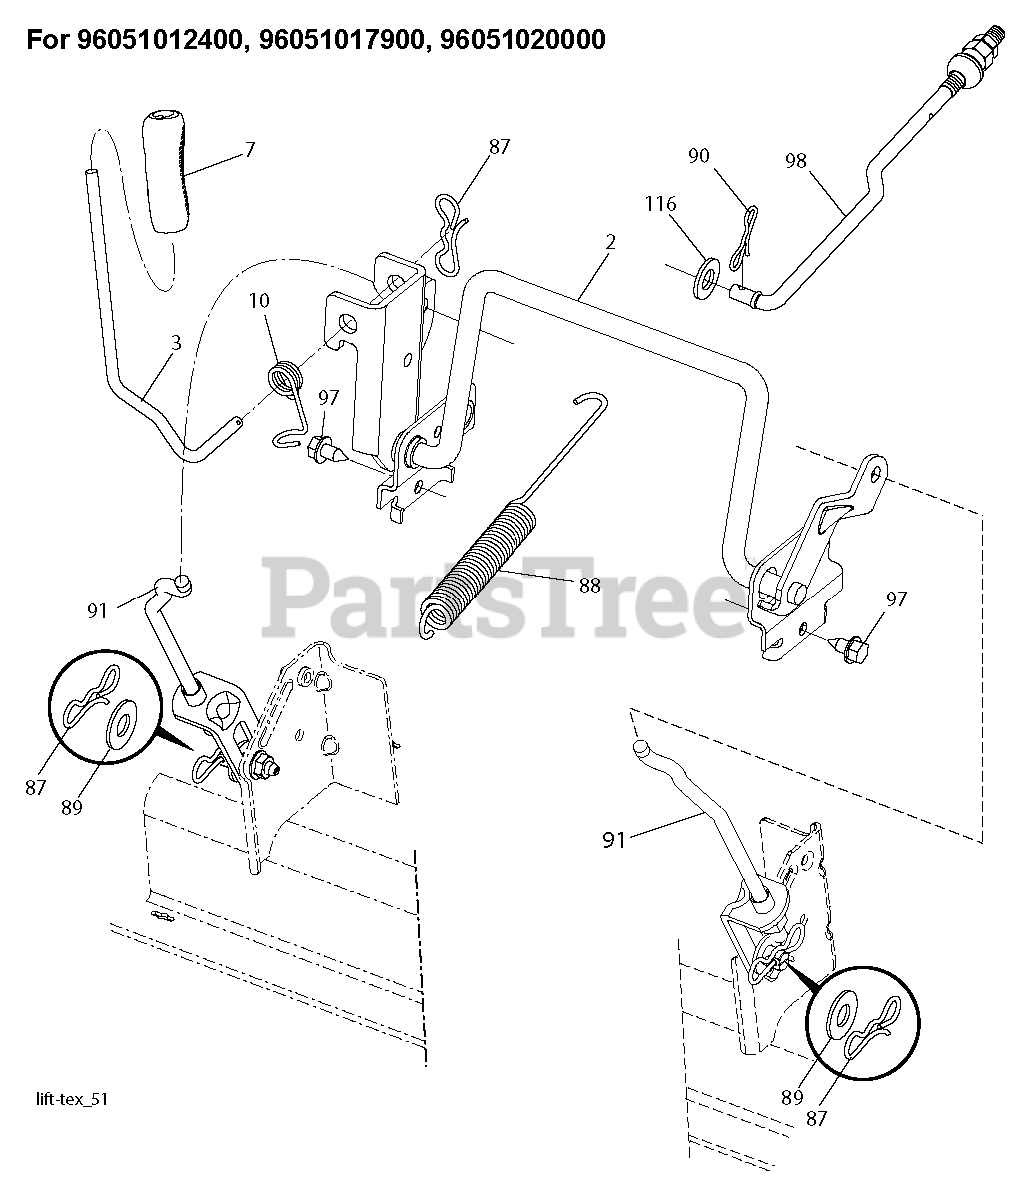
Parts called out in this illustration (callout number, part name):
2	SHAFT LIFT DECK WELD
7	GRIP.HANDLE.LIFT.PVC.BLACK
10	SPRING.TORSION.LIFT.HANDLE
87	PIN.COTTER.7/16.BOW TI.
88	SPRING.DK.LIFT.97/107.TXCRDII
89	WASHER.CLEAR.ZINC
90	PIN.COTTER.5/16.BOW TI
91	LINK.ASM.LIFT.REAR
91	Links
97	SCREW LT
97	Bolts
98	Links
